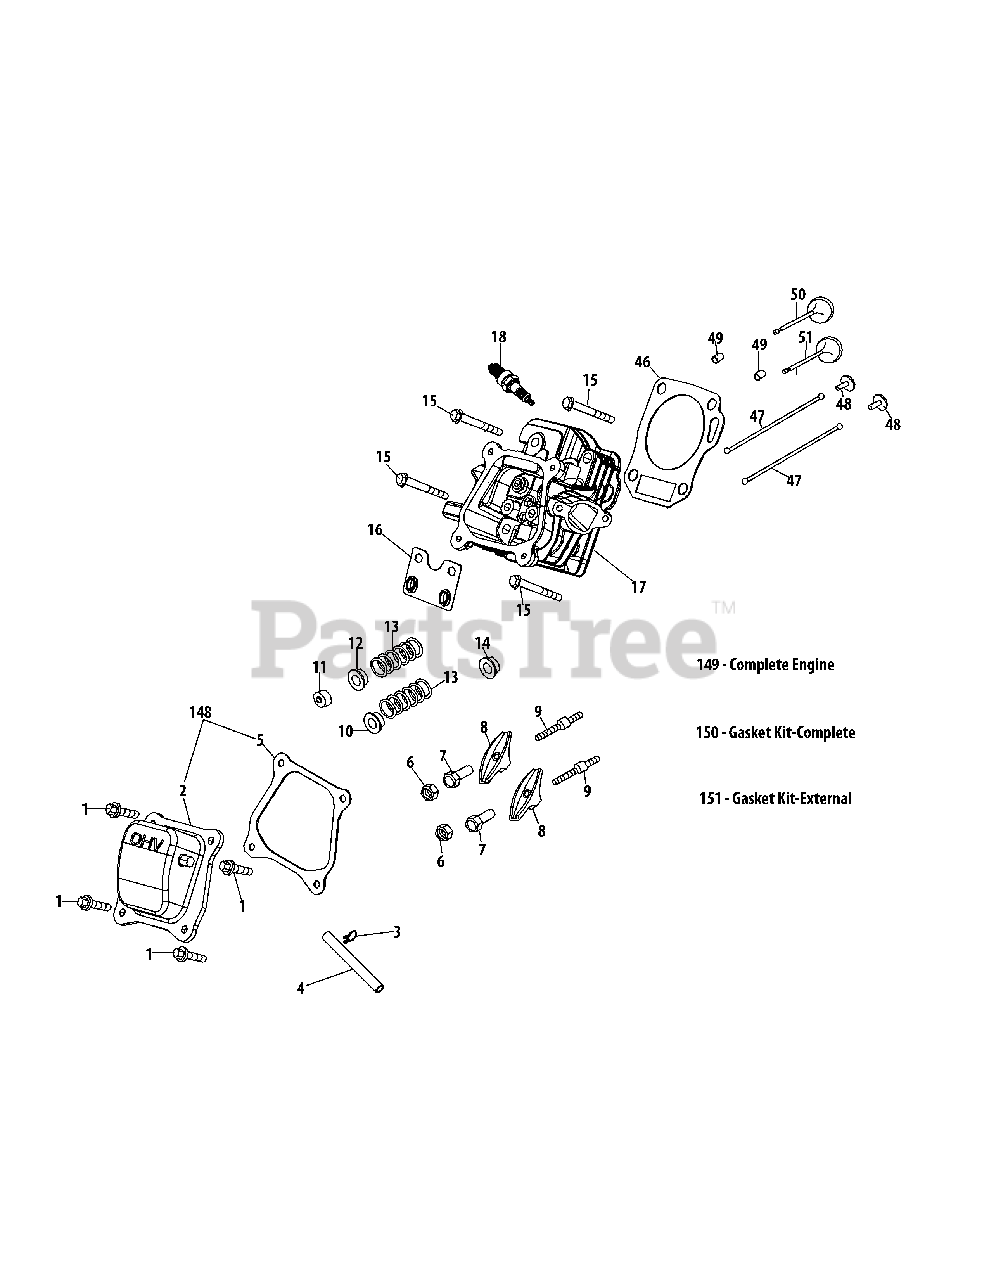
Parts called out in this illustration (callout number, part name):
1	Bolt M6×16
2	Valve Cover
3	Clamp, Fuel Hose
4	Venting Hose
5	Valve Cover Gasket
6	Nut, Pivot Locking
7	Adjusting Nut ,Valve
8	Rocker Arm
9	Bolt, Pivot
10	Valve Spring Retainer (Intake)
11	Exhaust Lash Cap
12	Valve Spring Retainer (Exhaust)
13	Valve Spring
14	Valve Seal (Intake)
15	Bolt M8×55
16	Push Rod Guide
17	Cylinder Head Assembly
18	Spark Plug/F6Rtc
46	Gasket, Cylinder Head
47	Kit-Push Rod
49	Dowel Pin 10×16
148	Valve Cover Kit
149	Complete Engine
150	Gasket Kit-Complete
151	Gasket Kit-External
